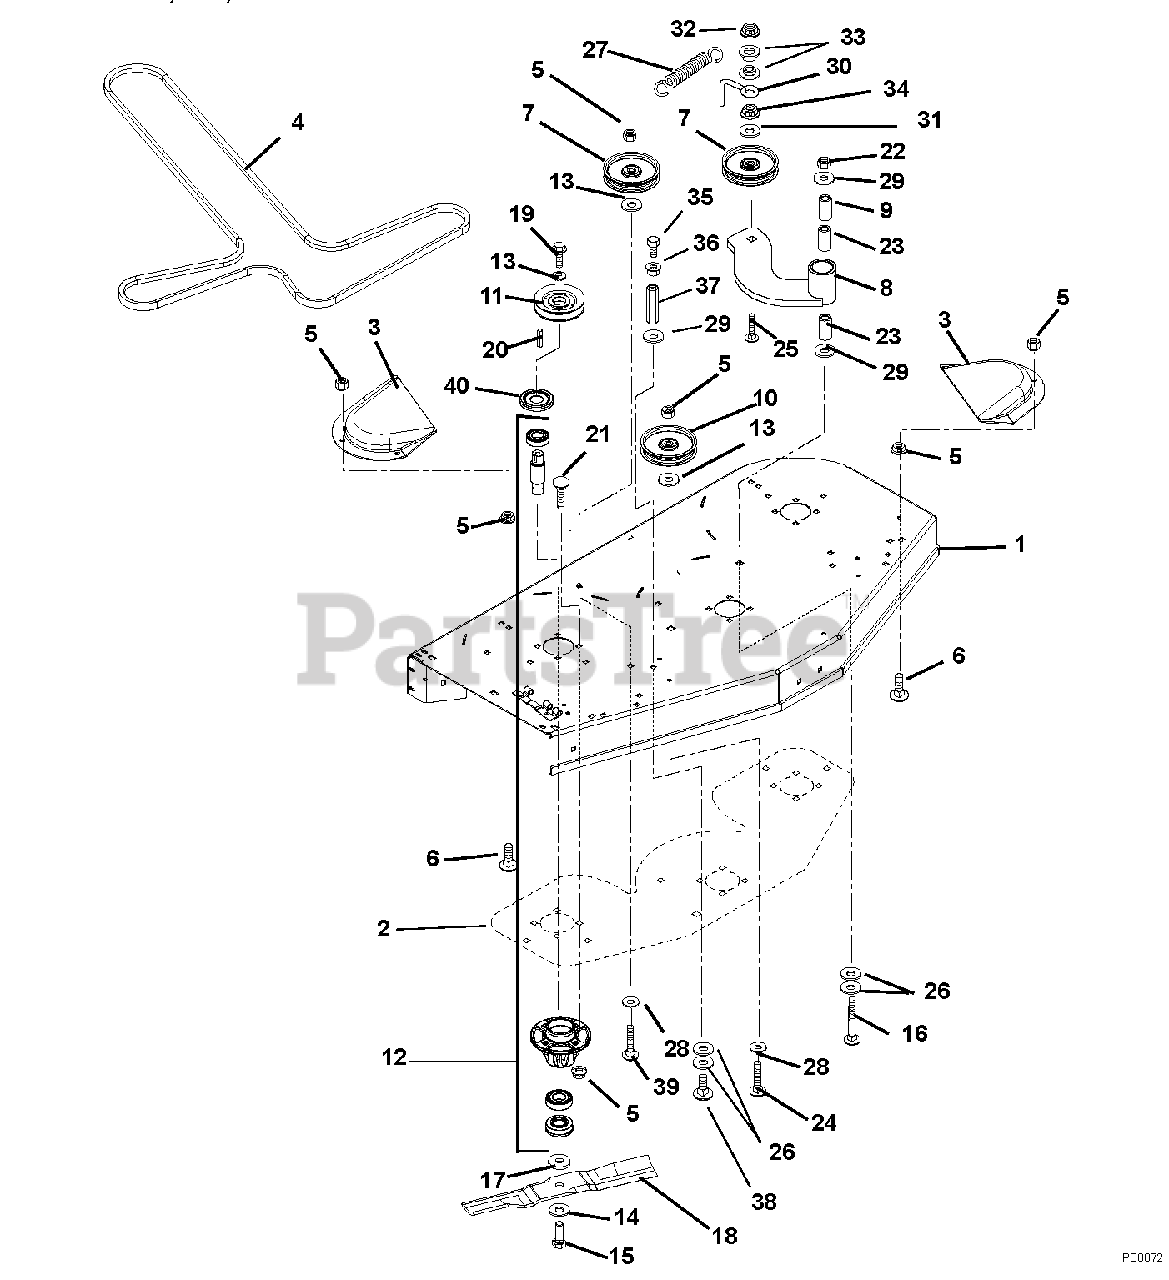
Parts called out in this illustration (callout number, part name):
1	40" Mower Deck (400)
2	Plate, 40" Doubler (400)
4	V-Belt (400)
5	Nut .38-16 Flange Nyloc
6	Bolt, Round Head Square Neck .38-16 x 1.25 Grade 5
7	Idler, Flat .38 x 4.00 x 1.06
8	Weldment, Idler Arm
9	Spacer, Powdered Metal
10	Pulley, Idler 4.00
11	Sheave, Spindle 4.25 Dia. (400)
12	Assembly, Spindle
13	Washer, Flat Steel .406 x 1.50 x .245
14	Washer, Bellville .63 x 1.625 x .140
15	Bolt, Hex .62-18 x 1.75 Grade 8
16	Bolt, Round Head Square Neck .50-13 x 3.50 Grade 5
17	Washer, Flat .64 x 1.81 x .25
18	Blade, Mower (13.88) (400)
19	Bolt, Hex .38-16 x 1.00 Grade 8 with Epoxy Patch
20	Key, Square .25 x .38 x .25
21	Bolt, Round Head Square Neck .38-16 x 1.50
22	Nut, Locking Top Flange .50-13
23	Bearing, 1.00 x 1.12 x .75
24	Bolt, Round Head Square Neck .38-16 x 2.00 Grade 5
25	Bolt, Round Head Square Neck .38-16 x 3.00 Grade 5
26	Washer, Flat Steel .755 x 1.375 x .062
27	Spring, Extension
28	Washer, Flat Steel .563 x 1.38 x .109
29	Washer, Flat Steel .515 x 1.625 x .25
30	Finger, Belt
31	Washer, Flat Steel .406 x 1.00 x .188
32	Nut, Locking Top Flange .38-16
33	Bushing, Sleeve .752 x .877 x .75 Bronze
34	Nut, Spiral Lock Flange .50-13
35	Bolt, Hex .50-13 x 2.00 Grade 5
36	Nut, Hex .50-13
37	Coupling .50-13 x 1.75
38	Bolt, Round Head Square Neck .50-13 x 1.25 Grade 5
39	Bolt, Round Head Square Neck .38-16 x 2.75 Grade 5
40	Cap, Dust
